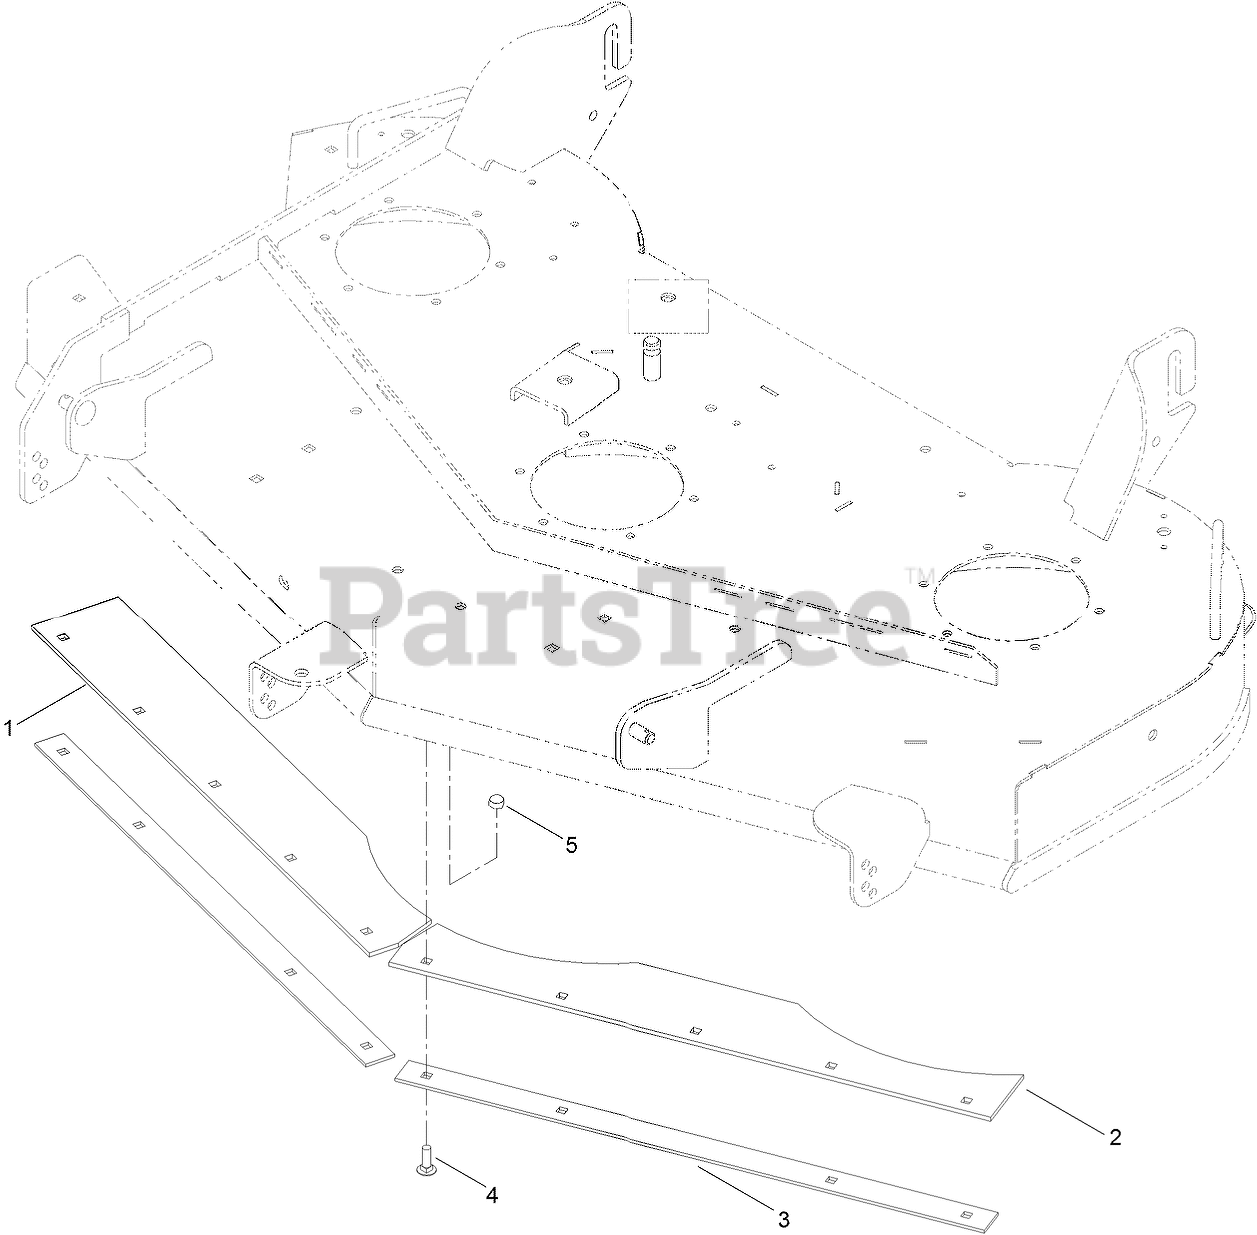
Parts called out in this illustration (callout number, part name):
1	SKIRT-RUBBER, RH
2	SKIRT-RUBBER, LH
3	PLATE-SKIRT
4	BOLT-CARR
5	NUT-HEX
